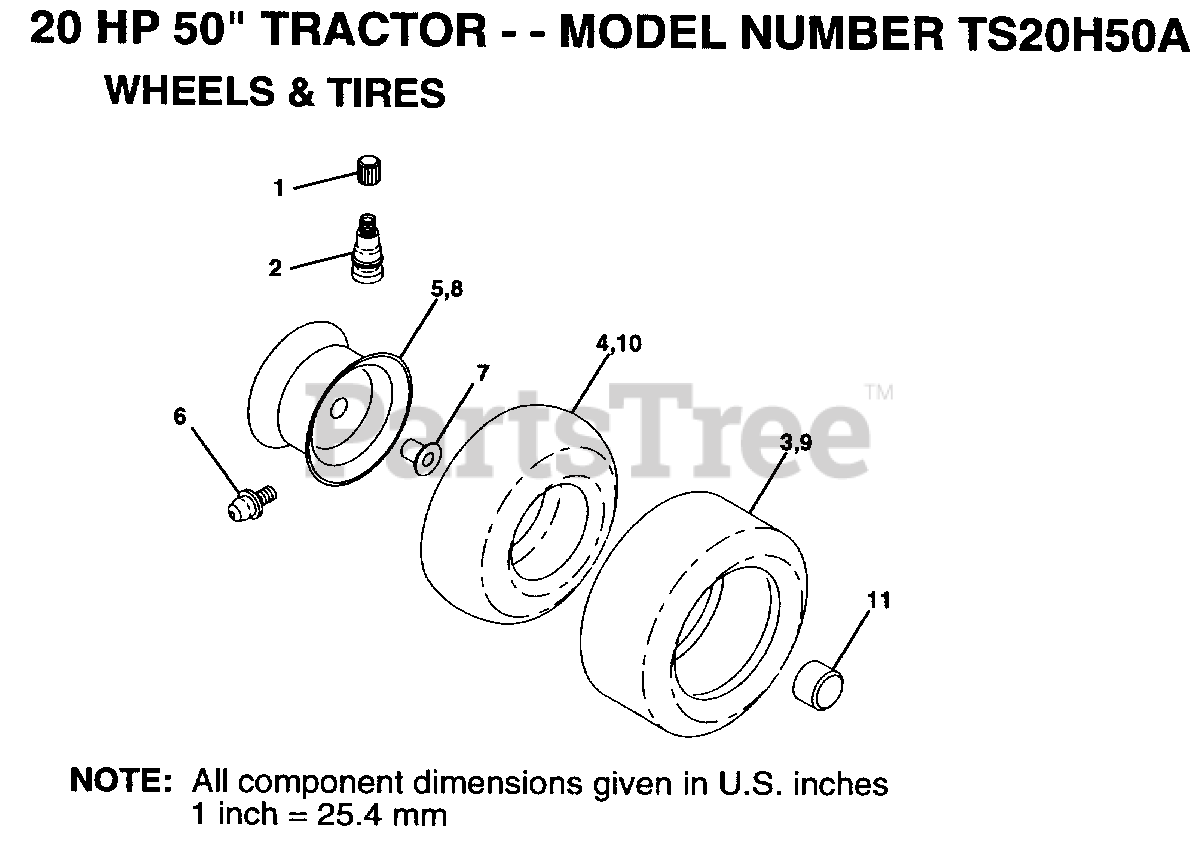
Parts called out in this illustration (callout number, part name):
1	VALVE CAP
2	VALVE STEM LT
4	TUBE.16X6.5/7.5-8
5	RIM.FRONT.
6	ZERK FITTING M
7	"FLANGE, BEARING"
8	"WHEEL,REAR"
10	TUBE.23X8/10-12
11	HUB CAP
12	FITTING LT
